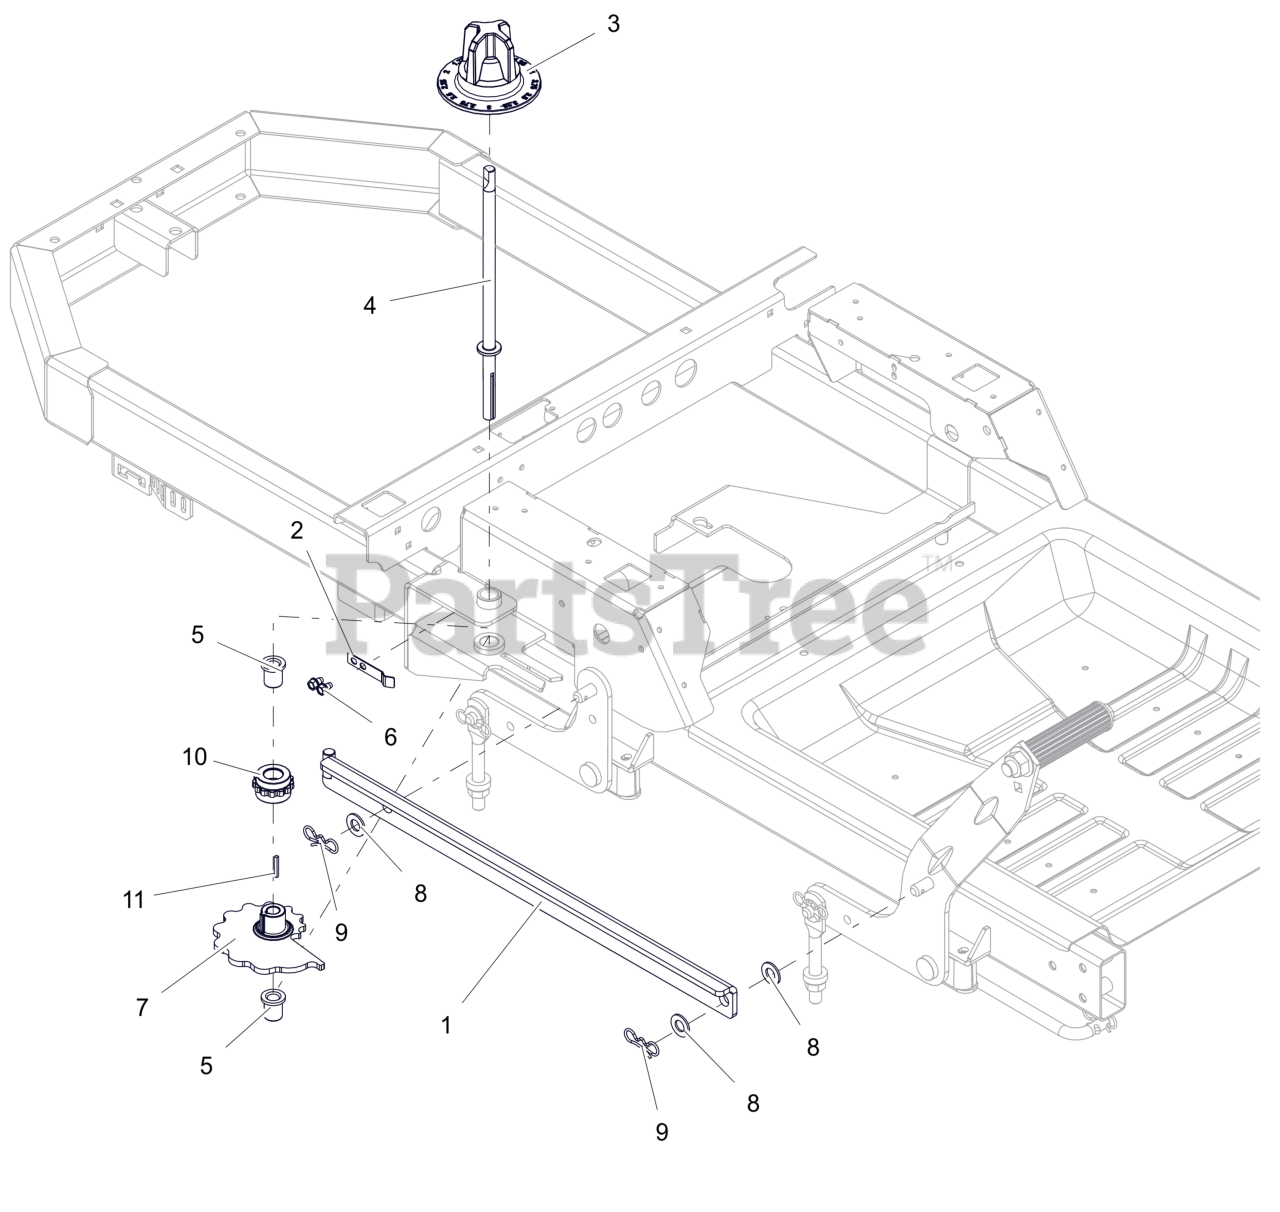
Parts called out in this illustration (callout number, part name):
1	WLDMT, HOC LINK
2	ARM, HOC DETENT
3	KNOB, HOC DIAL
4	SHAFT, CAM
5	BSHG-FLG, .503X.750X.875X1.00
6	SCR,TAP .25-20X.375 HWH TR ZCC
7	CAM, HOC (PM)
8	WSHR-FL-NYL .518X1.000X.080
9	PIN, BOWTIE .091X1.875 ZCC
10	GEAR, HOC INDEX
11	KEY, 1/8 X 1/8 X 1.0
